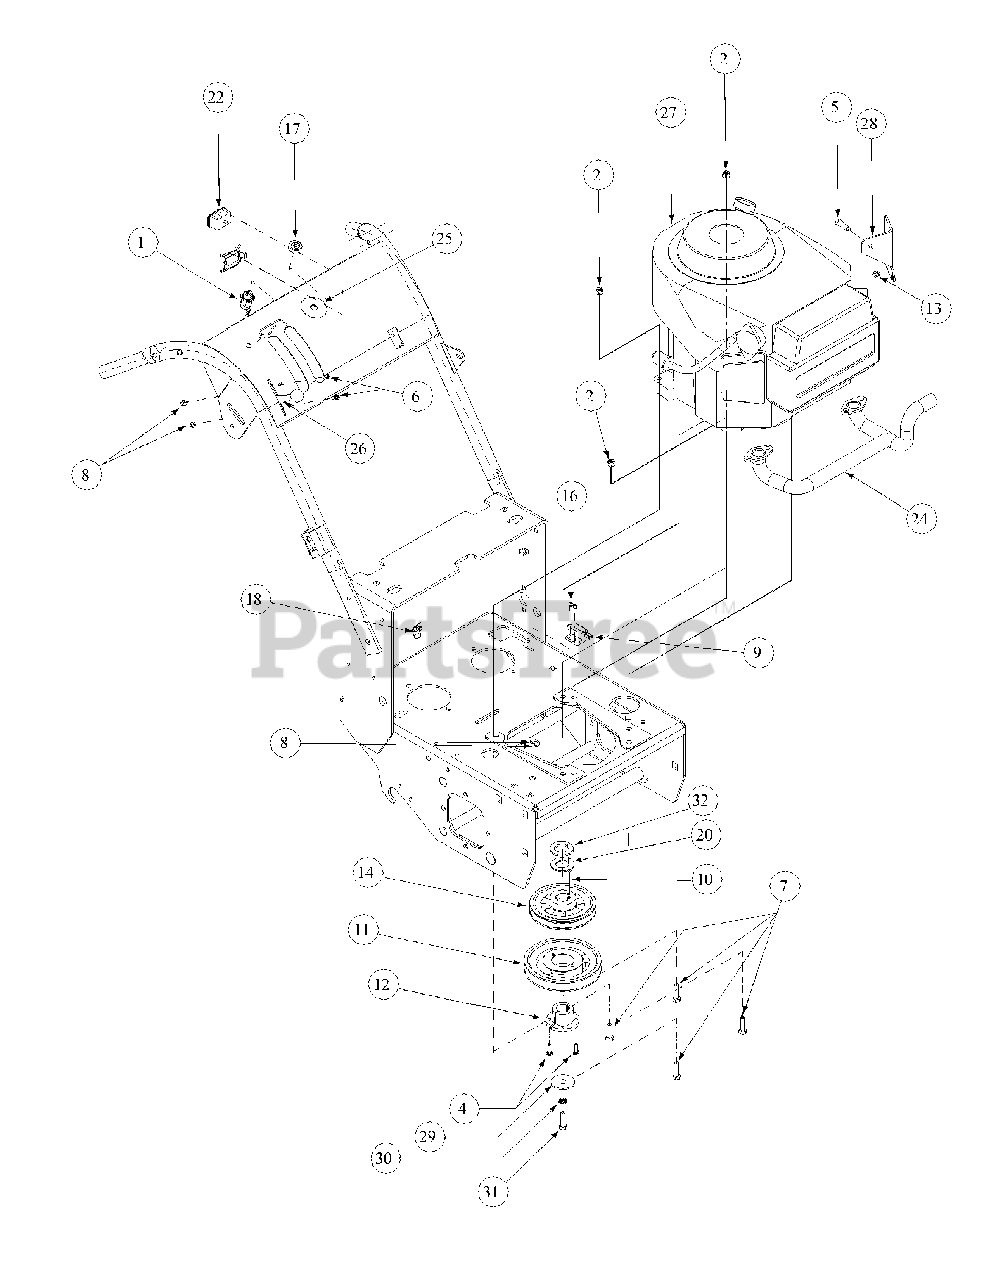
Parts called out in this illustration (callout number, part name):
1	On/Off Ignition Switch
2	Nylock Nut, 5/16-18
4	Hex Cap Screw, 1/4-20, .75
5	Hex Cap Screw, 5/16-18 x 3/4
6	Slotted Hex Washer Screw, 10-32 x 1/2
7	Hex Cap Screw, 5/16-18 x 2
8	Lock Nut, Nylon Insert, #10-32
9	Delta Switch, #5100-51
10	Key Stock, 1/4 x 1/4 x 2
11	Deck Pulley
13	Hex Nut, Center Lock, 5/16-18
14	Sheave 1" Bore w/2 Set Screws
15	Belt, Hydro Pump
16	Phil. He. Mach. Screw #10-32 x 5/8
17	Nut w/Cap, 5/8-32 Ignition
18	Support Clamp, 3/8 OD
19	Harness Wire
20	Flat Washer
22	Hour Meter
23	Harness Hourmeter
24	Kawasaki Manifold
25	Decal, Pull Start Overlay
26	Throttle Control w/Detent, 57.2
27	Kawasaki Engine, 15HP
28	Muffler Kawasaki Bracket
29	Clutch Washer
30	Lock Washer, 7/16
31	Capscrew, 7/16-20 x 1-1/4
32	Spacer Pulley Engine
